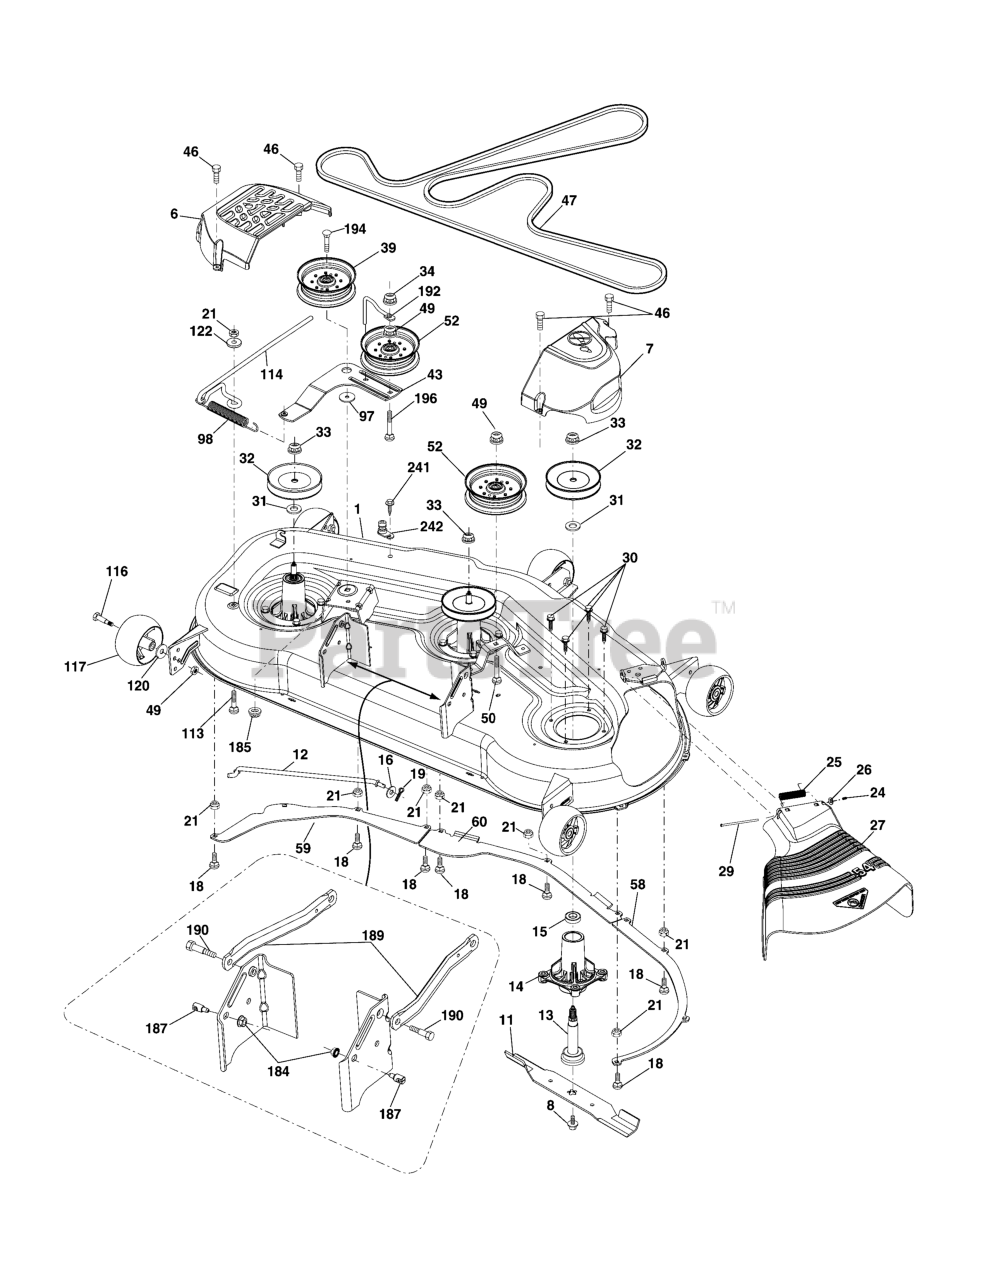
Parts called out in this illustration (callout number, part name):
1	Deck Weldment Mower
6	Cover Mandrel LH
7	Cover Mandrel RH
8	Bolt 7/16 Asm. Blade
11	Blade Bagging
12	Rod Anti-Sway
13	Shaft Asm. w/Lower Bearing
14	Housing, Mandrel
15	Bearing, Ball, Mandrel
16	Washer 13/23 x 13/16 x 1 2 Ga.
18	Bolt RdHd. 5/16-18 unc x 5/8
19	Pin Cotter 5/16 Bowtie Lock
21	Nut, Crownlock 5/16-18 unc
24	Cap Sleeve
25	Spring, Torsion
26	Nut, Push
27	Deflector Shield
29	Rod, Hinge
30	Screw, Thdrol. Washer Head
31	Washer, Spacer Mower Vented
32	Pulley, Mandrel
33	Nut, Flg. Top Lock
34	Nut Crownlock 3/8-16 unc
39	Pulley, Idler
43	Arm, Idler
46	Screw, Thdrol. 1/4-20 x 5/8
47	Belt Drive Deck
49	Nut, Lock Flg. 3/8-16 unc
50	Bolt Rdhd. Sqnk. 3/8-16 unc x 2
52	Pulley Idler
58	Baffle Right
59	Baffle Left
60	Baffle Center
97	Washer Hardened
98	Spring Drive
113	Bolt Rdhd. Sqnk. 5/16-18 x 3/4
114	Rod Tension Relief
116	Bolt, Shoulder
117	Gauge Wheel
120	Washer 13/32 x 1-1/4 x 12 Ga.
122	Bushing Tension Relief
184	Nut Lock Hex Flange 5/16-18
185	Nut Lock Flange 7/16-14 Gr. 5
187	Stud Fastener w/"D" Anti-Rotation
189	Arm Susp. Mower Rear
190	Bolt Shoulder
192	Keeper Belt Idler
194	Bolt Carr. Sqnk. 7/16-24 x 2
196	Bolt Rdhd 3/8-16 x 2-1/2 Gr. 5
241	Screw
242	Port Washout
